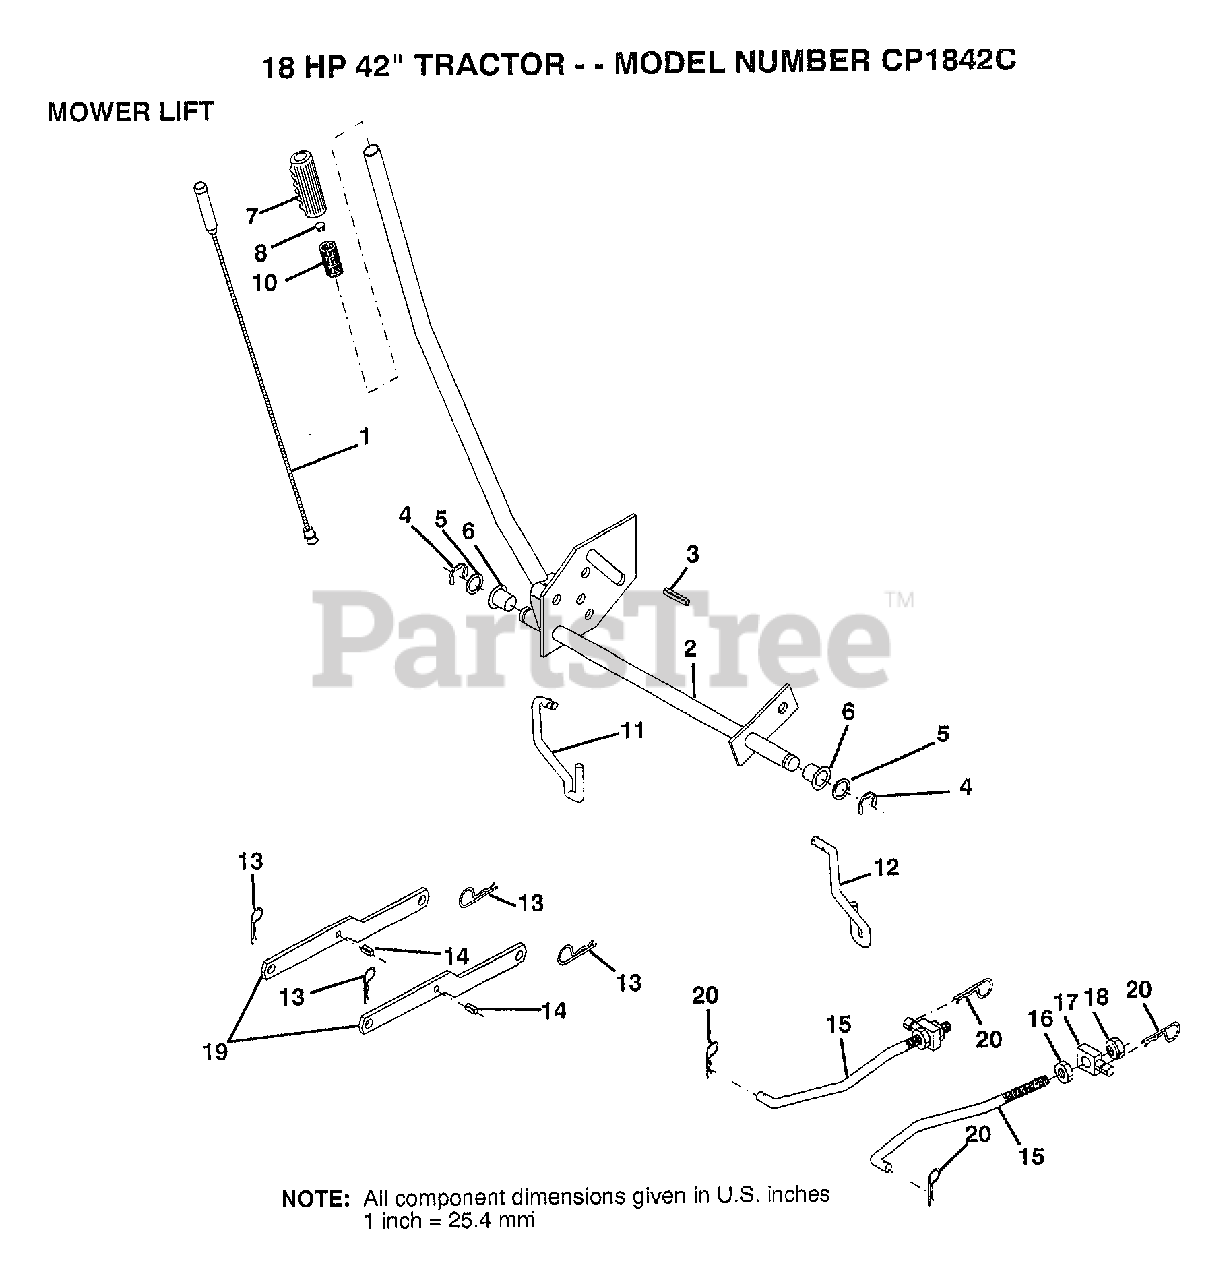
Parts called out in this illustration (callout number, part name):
1	WIRE ASM
2	SHAFT.ASM.LIFT LH
3	PIN GROOVE
5	WASHER
6	NYLON BEARING
7	GRIP
11	LINK LIFT LH
12	LIFT LINK RH
14	"PIN,SPRING"
15	LINK.FRONT
16	NUT
17	TRUNION
18	NUT.LK.W/WSH.1/2.
20	RETAINER.SPRING
